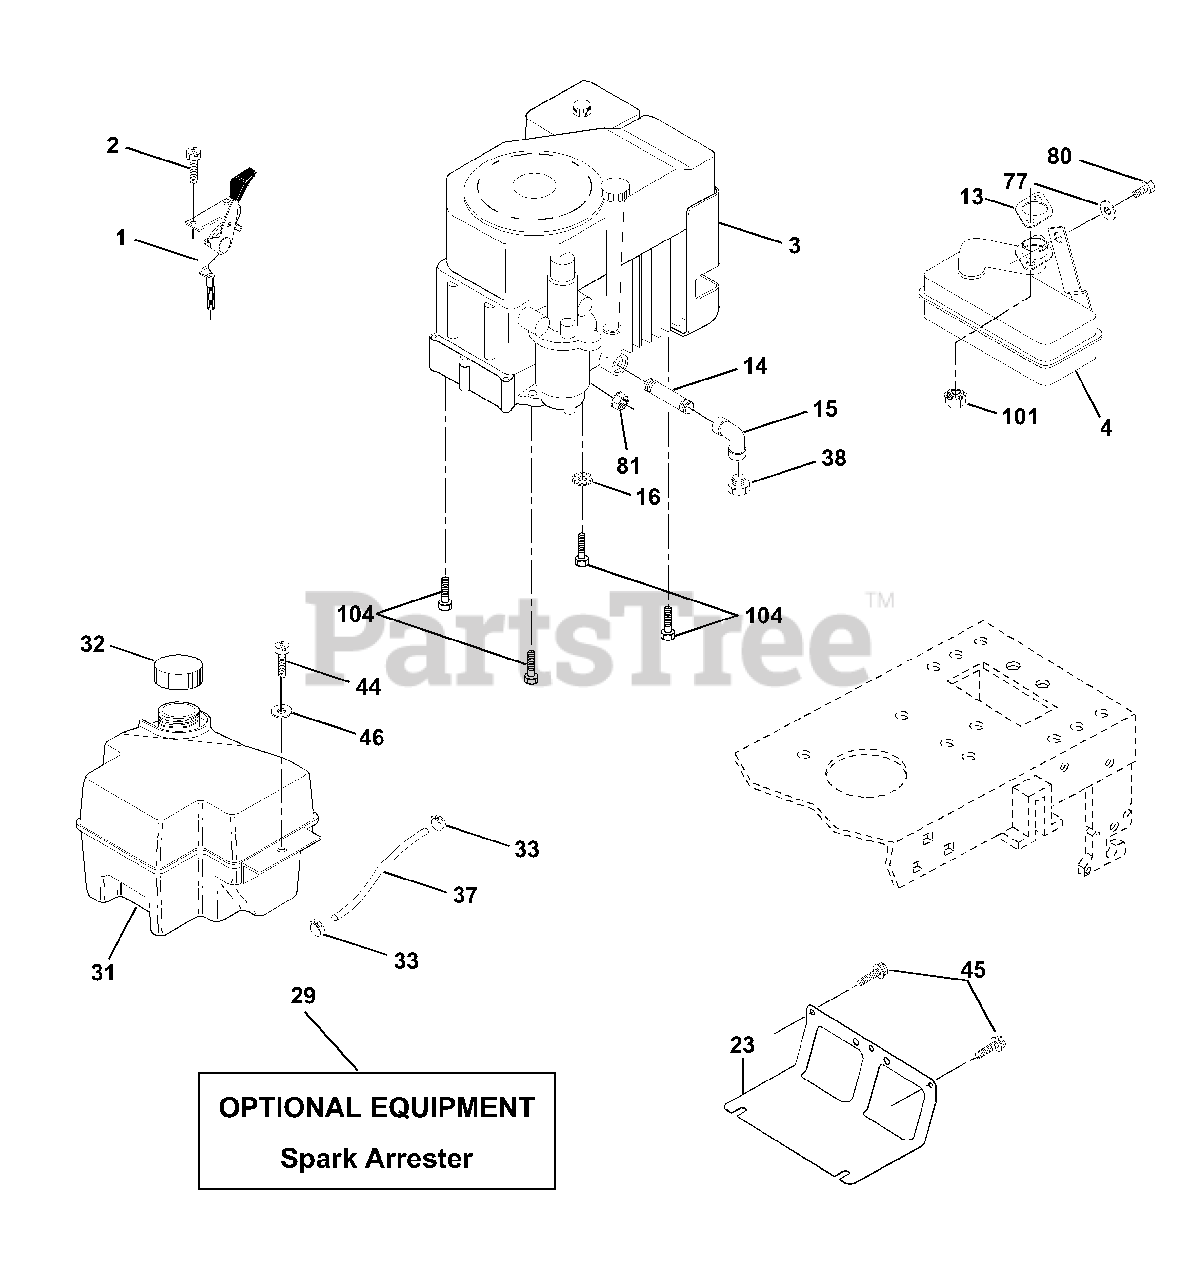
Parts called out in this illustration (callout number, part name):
1	Control Th/ch Flag
2	Screw Hex Thd Cut 1/4-20x5/8 T
4	Muffler Exhaust
13	Gasket Muffler
14	Tube Drain Oil Easy
16	Washer Lock Ext Tooth 3/8
23	Shield Brn/Dbr Guard
29	Arrestor Spark
31	Tank Fuel Front 2 00
32	Cap Fuel
33	Clamp Hose Black
37	Line Fuel 20"
38	Plug Drain Oil Easy
40	Bushing Snap Nyl Blk Fuel Line
44	Screw Hex wsh Thdrol 1/4-20x3/4
45	Screw Hex Wsh Thdrol 3/8-16 x 3/4
46	Washer 9/32 X 7/8 X 16 Ga
77	Washer 5/16 x 3/4 x 16 Ga.
80	Bolt Hex Hd. 5/16-18 Unc x 1/2
81	Nut Keps Hex 1/4-20 Unc
101	Nut Flange
105	Screw 3/8-16 x 1
